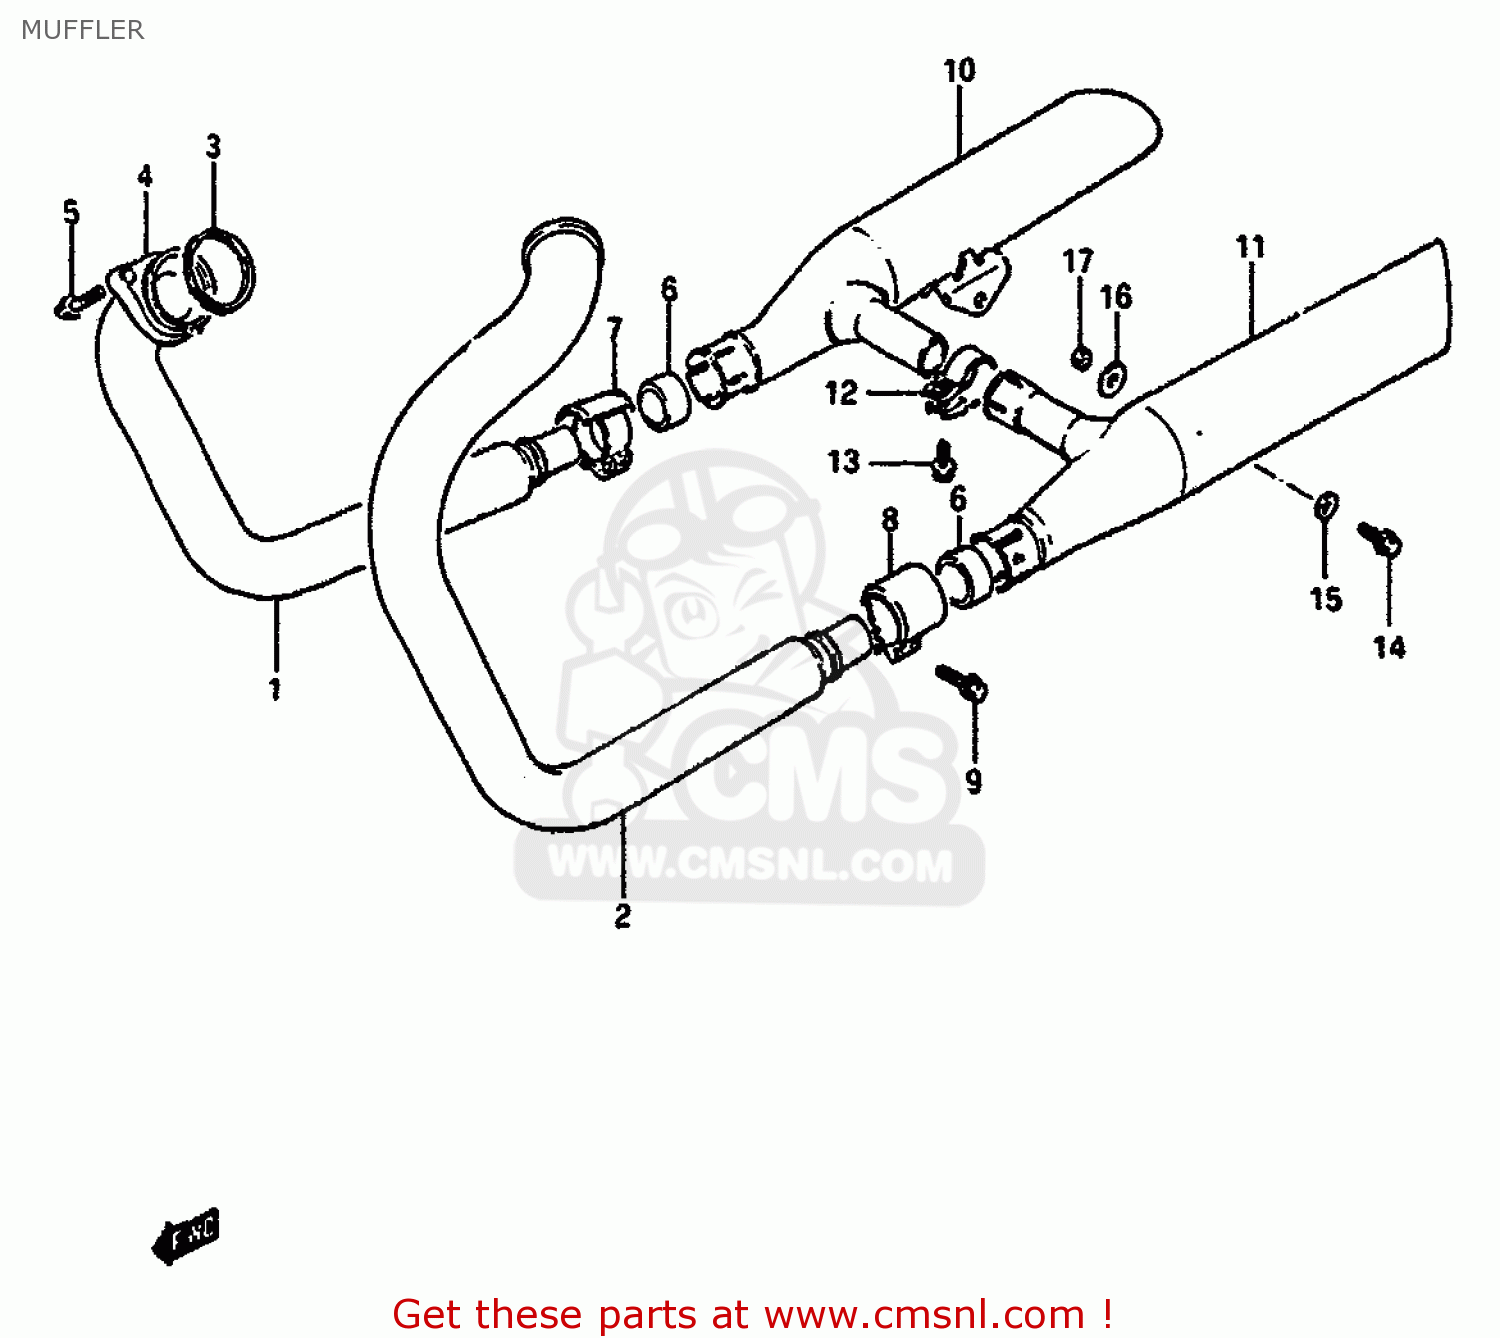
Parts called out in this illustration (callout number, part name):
1	PIPE,EXHAUST
2	PIPE,EXHAUST
3	GASKET,EXHAUST PIPE (NAS)
4	CLAMP,EXHAUST PIPE
5	BOLT(8X35)
6	CONNECTOR,MUFFLER
7	CLAMP,MUFFLER CONNECTOR,R
8	CLAMP,MUFFLER CONNECTOR,L
9	BOLT
10	MUFFLER,RH
11	MUFFLER,LH
12	CLAMP,EXHAUST COUPLER
13	BOLT 6X25
14	BOLT
15	WASHER
16	WASHER
17	NUT
